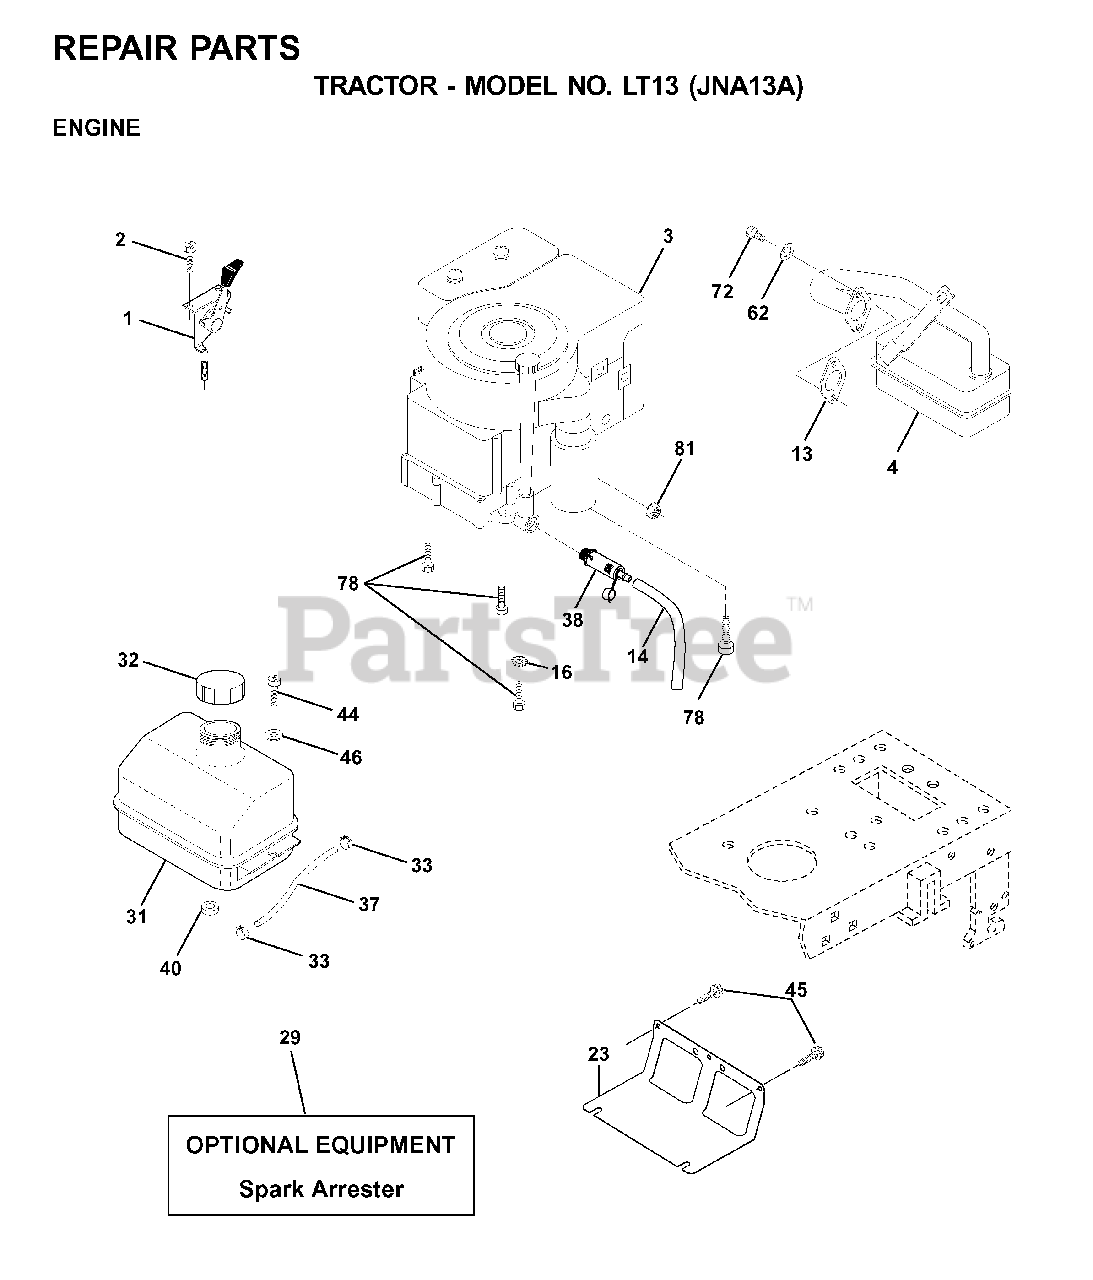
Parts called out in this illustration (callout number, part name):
1	CONTROL TH/CH FLAG
2	SCREW LT
13	REPL BY 532 27 22-93
14	TUBE, DRAIN OIL ASM.
16	LOCKWASHER
23	SHEILD.BROWNING.DBR.GUARD
29	ARRESTER SPARK (OPTIONAL)
32	FUEL CAP
33	HOSE CLAMP
37	LINE.FUEL.20
38	PLUG, OIL DRAIN EASY
40	GROMMET T
44	SCREW HEXWSHR 1/4-20X3/4
45	SCREW, 3/8-16X3/4
46	WASHER
62	LOCKWASHER
72	SCREW
78	SCREW.3/8-16
81	NUT
